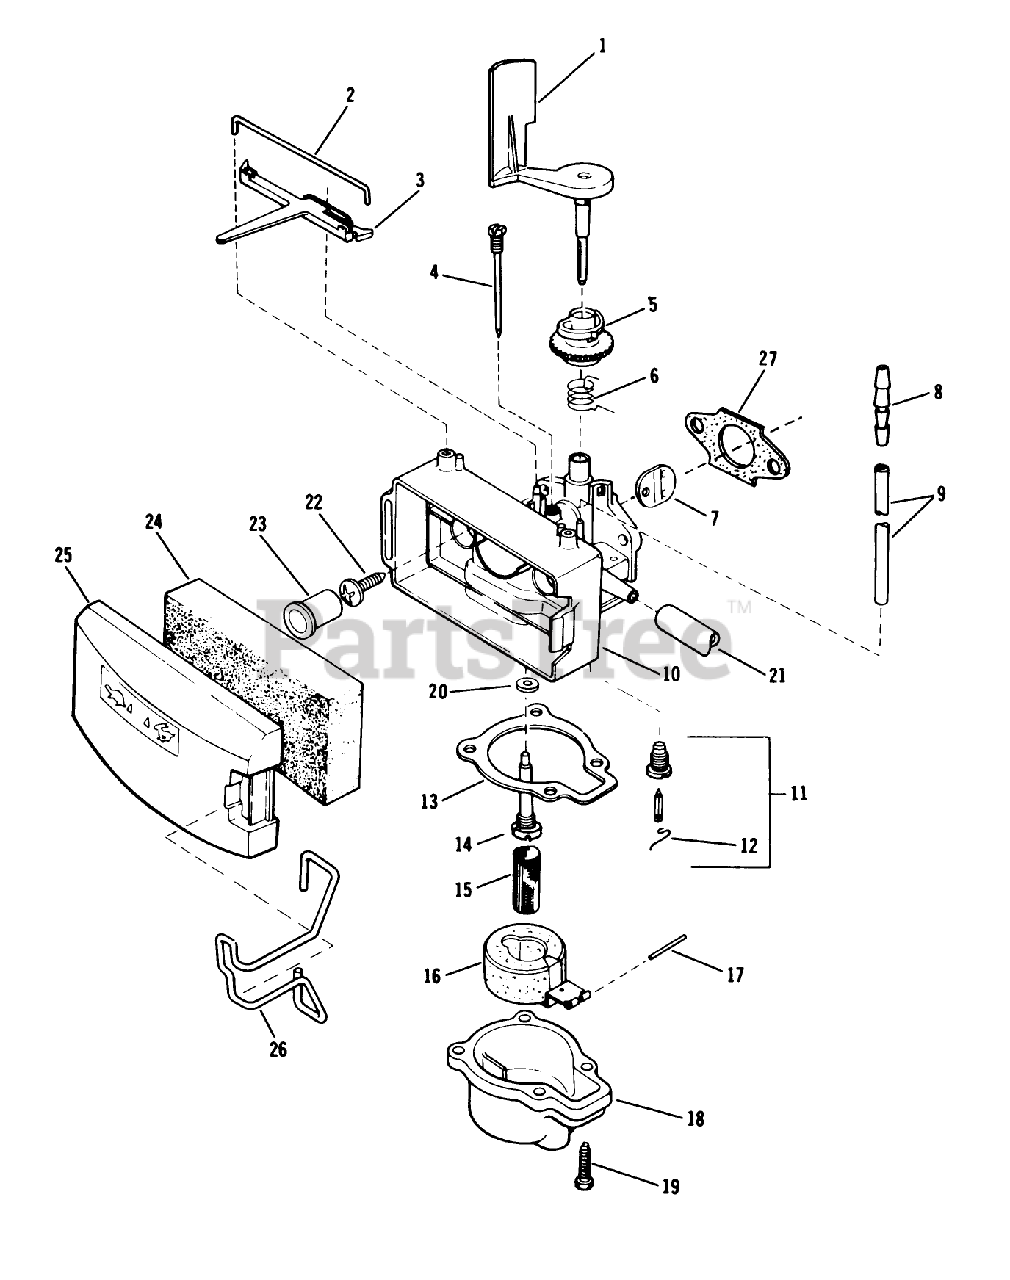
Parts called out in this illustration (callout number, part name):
2	RETAINER
3	LEVER S
4	NEEDLE ADJ. AY S
5	COLLAR-ADJUST, AIRVANE
6	SPRING,THROTTLE S
7	DISC S
8	GASKET CARB S
9	TUBING-PRIMER S
10	CARB BODY S
14	NOZZLE SER KIT S
15	FILTER-FUEL VS
19	SCREW-HH
20	WASHER
21	RETAINER-COVER, FILTER
22	SCREW
